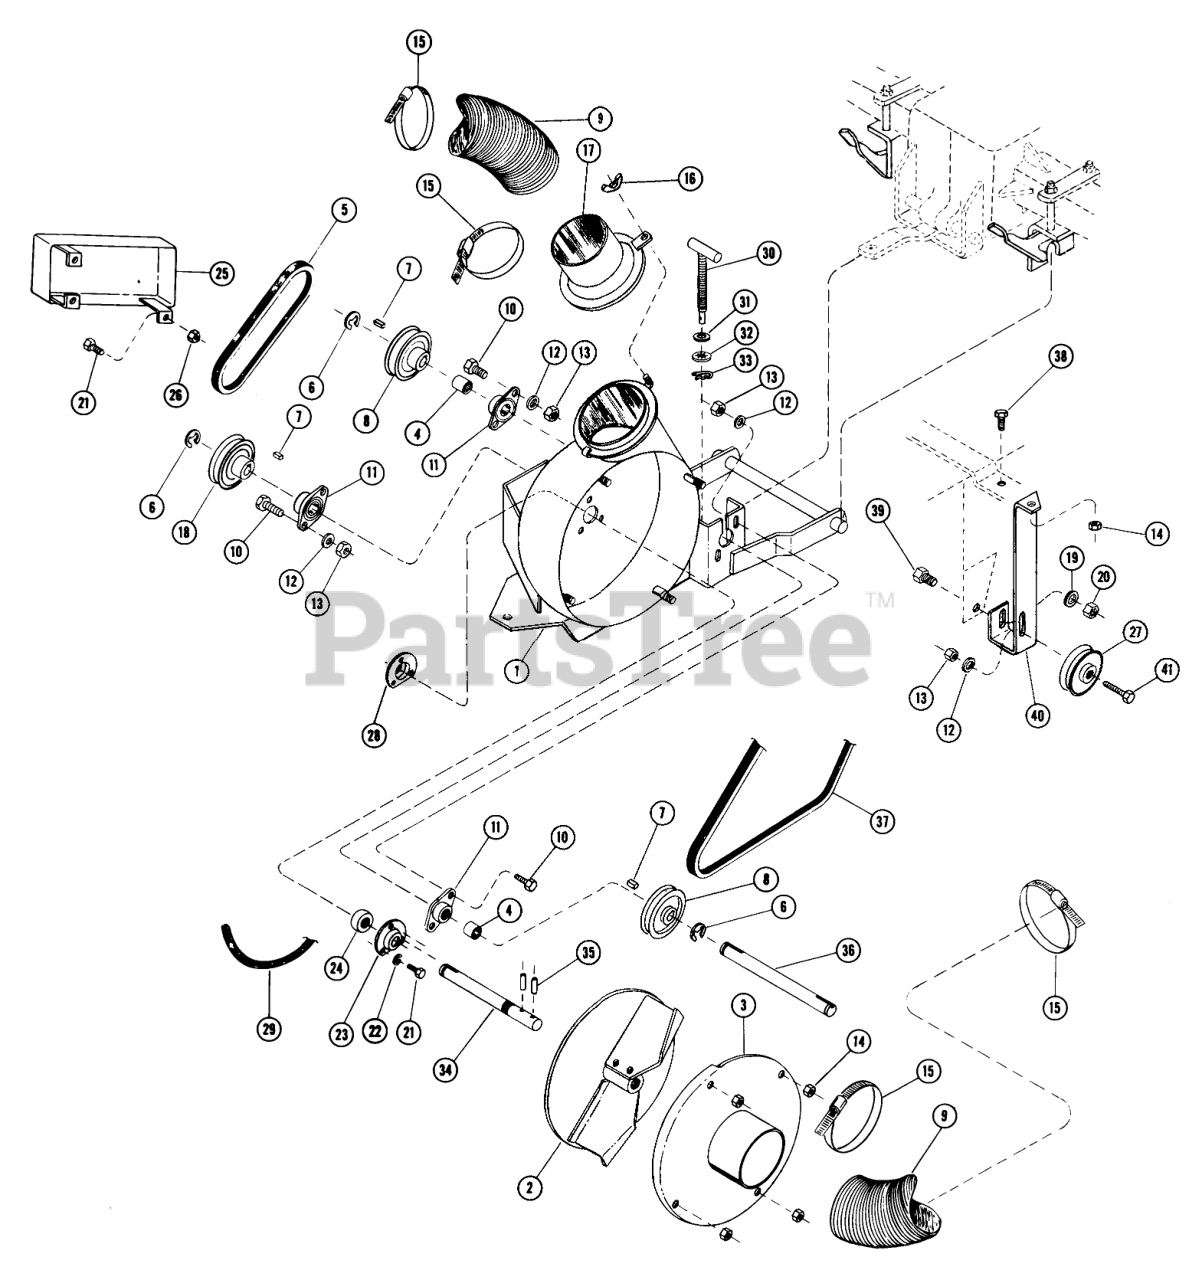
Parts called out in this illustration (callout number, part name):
1	Impeller Housing Assembly
2	Impeller
3	Front Plate
4	SPACER
5	V BELT
6	E-Ring 3/4
7	KEY
8	PULLEY
8	Set Screw
9	6" Dia. Hose x 51"
10	Bolt
11	Jackshaft Bearing
12	Washer
13	Nut
14	Nut
15	CLAMP
16	WING NUT
17	TRANSITION HOSE
18	Impeller Pulley
19	Washer
20	Eslok Nut
21	Bolt
22	Washer
23	BEARING-CUP
24	BEARING-BALL
25	Belt Cover Assembly
25	DECAL-WHEEL HORSE
26	Nut
27	IDLER
28	BEARING-CUP W/NUTS
30	Adjustment Screw
31	7/16 Flat Washer
32	7/16 Push-Nut PS-438014
33	Hairpin Cotter
34	SHAFT
35	ROLL PIN 1/4 X 1-1/4
36	JACK SHAFT
37	V-BELT
38	Bolt
39	Bolt
40	Idler Mounting Bracket
41	BOLT
